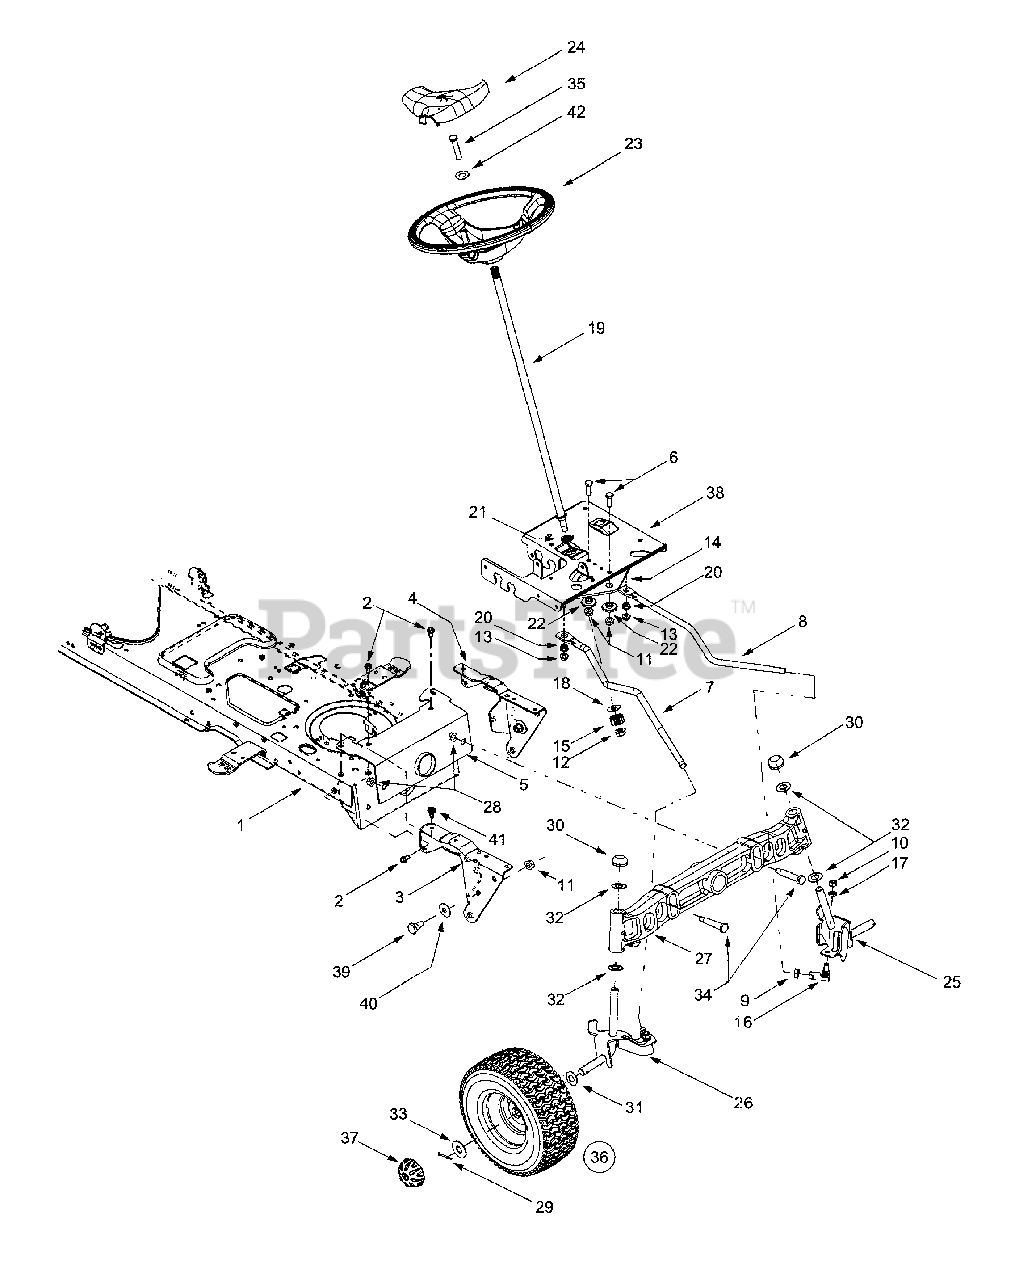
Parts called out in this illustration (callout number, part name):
6	Hex Cap Screw, 3/8-16 x 1 (Grade 5)
7	RH Drag Link
8	LH Drag Link
9	Jam Nut, 7/16-20 (Grade 2)
10	Hex Nut, 3/8-24 (Grade 2)
11	Flange Lock Nut, 3/8-16
12	Flange Lock Nut, 7/16-20
13	Flange Lock Nut, 5/16-18
14	Steering Gear, 11/90 Ratio
15	Steering Pinion Gear
16	Ball Joint, 7/16-20
17	Lock Washer, 3/8
18	Flat Washer, .51 x 1.12 x .06
19	Steering Shaft, .625 OD x 24.4
20	Plastic Bushing, .38 ID
21	Hex Flange Bearing, 5/8
22	Shoulder Spacer, .38 ID
23	Soft Touch Steering Wheel
24	Steering Wheel Cap
25	LH Axle Assembly, .625 Diameter
26	RH Axle Assembly, .625 Diameter
27	Cast Iron Pivot Bar w/ Fittings, .625
28	Flange Lock Nut, 3/8-16
29	Cotter Pin
30	Push Cap, .625
31	Flat Washer, .64 x 1.0 x .12
32	Flat Washer, .64 x 1.24 x .06
33	Flat Washer, .635 x 1.589 x .06
34	Shoulder Screw, .5 x 2.2, 3/8-16
35	Hex Bolt, 5/16-18 X 1
37	Hub Cap
39	Shoulder Screw, 3/8-16
40	Bell Washer, .39 x 1.13 x .062
41	Self-tapping Screw, 5/16-18 x .75
42	Bell Washer, .34 x .872
